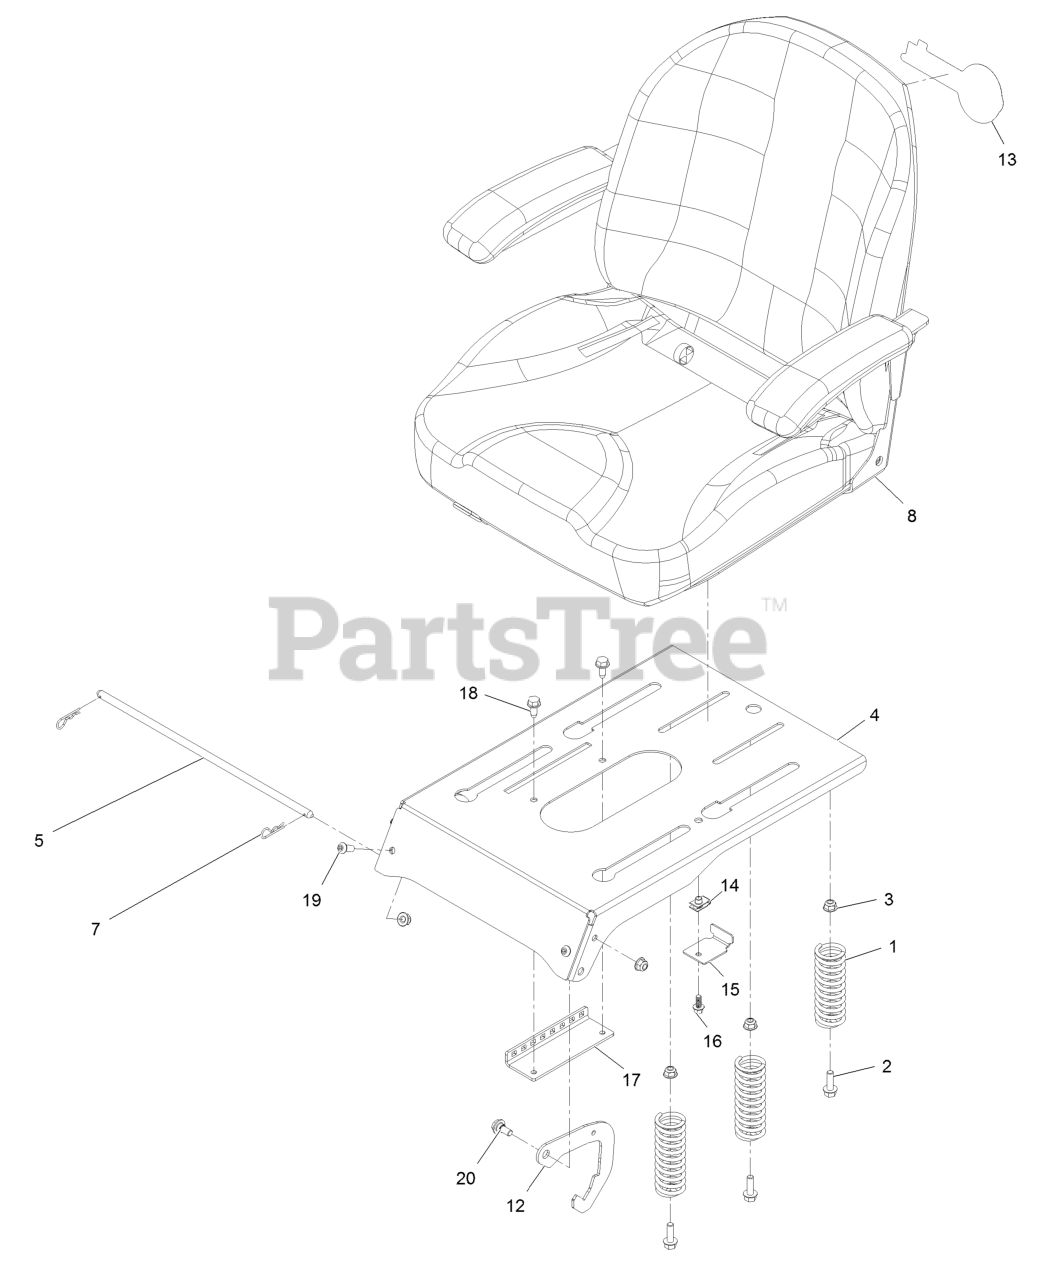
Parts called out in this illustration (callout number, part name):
1	SPRING-COMPRESSION
2	SCREW-HHF
3	NUT-HF, NI
4	PAN-SEAT, DELUXE
5	ROD-PIVOT, NARROW
7	PIN-COTTER
8	SEAT ASM, EXMARK
12	LATCH-SEAT
13	DECAL-EXMARK LOGO
14	Nut-Retainer-Panel 1/4-20
15	BRACKET-STOP, SEAT
16	SCREW-HHF
17	BRACKET-LATCH, SEAT
18	Screw-HWH 5/16-18 X 3/4 Tf
19	SCREW-HSBH
20	SCREW-SHOULDER
